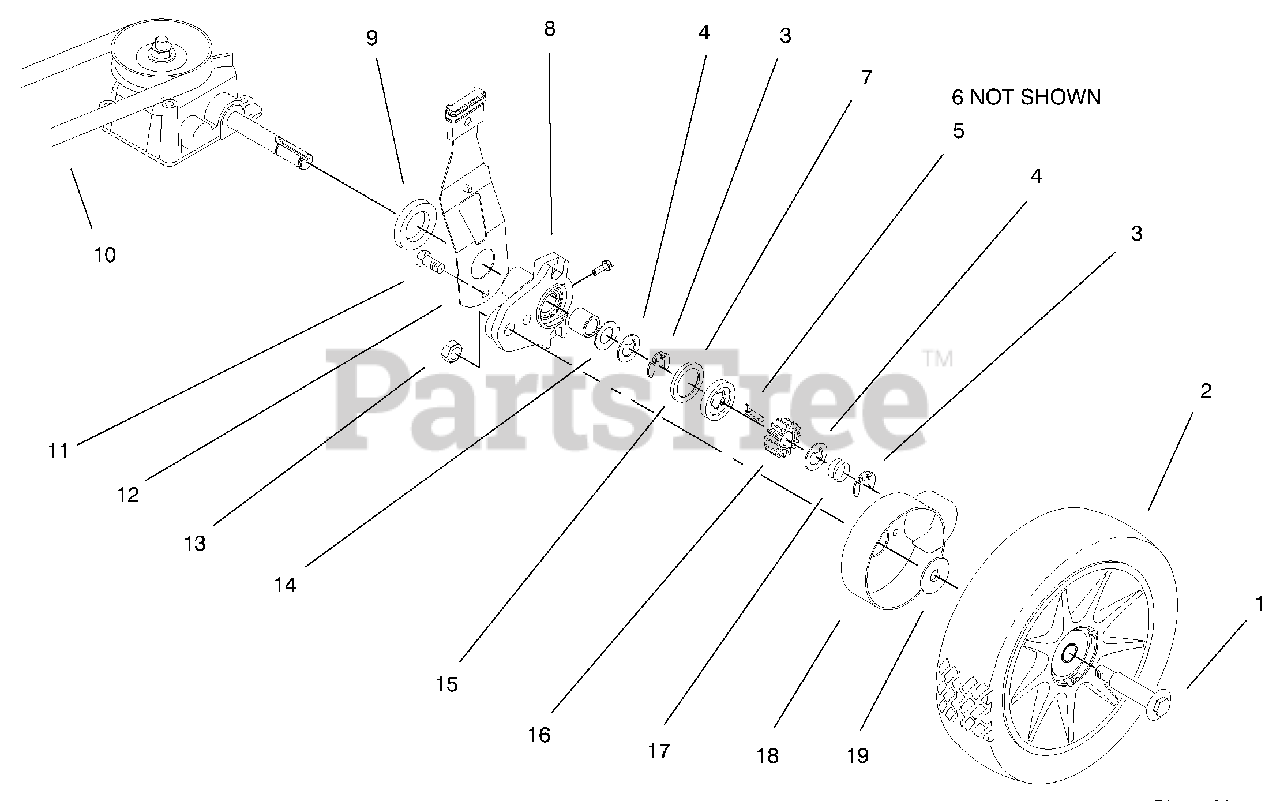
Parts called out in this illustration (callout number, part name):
1	Bolt-Shoulder
3	Ring-Retaining
4	Washer-Thrust
5	Key-Rocking LH
6	Key-Rocking RH
7	Ring-Friction
8	ASM-Hgt Adj Arm
9	Spacer-Axle Shaft
12	ASM-Spring Arm
13	Nut-Lock
14	Washer-Thrust
16	Gear-Pinion
17	Spring-Compression
18	Cover-Wheel
19	Washer-Stepped
